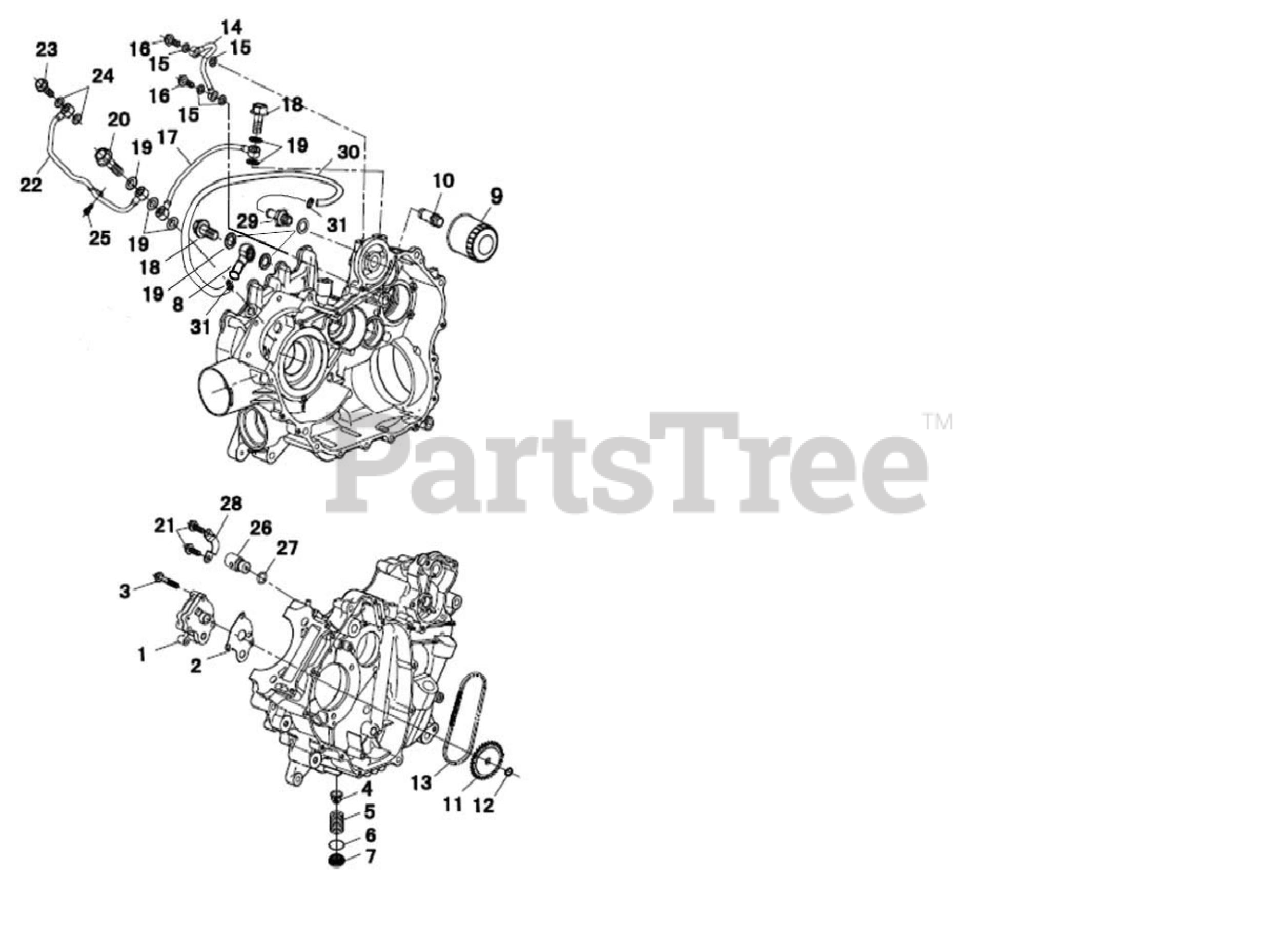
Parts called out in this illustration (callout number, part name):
1	Oil Pump Assy
2	Gasket,Oil Pump
3	Hex flange bolts M6X40
4	Oil Filter Strainer
5	Filter Spring
6	O-Ring 36X3.5
7	Blind Nut,Oil Drainage
8	BANJO BOLT
9	Oil Filter
10	Filter joint
11	Oil Pump Driven Sprocket
12	Circlip for shaft ?11
13	Chain,Oil Pump
14	Oil Tube Welding Assy A
15	Aluminum Washer 8X15X2
16	Bolts for oil tube M8X25
17	Oil Tube Welding Assy B
18	Bolts for oil tube M14X1.5X28
19	Aluminum Washer 14X20X1.5
20	Bolts for oil tube M14X1.5X50
21	Hex flange bolts M6X14
22	OIL TUBE WELDING ASSEMBLY
23	Bolts for oil tube M10X1.25X30
24	Aluminum Washer 10X16X1.2
25	Hex flange bolts M6X12
26	Pressure Regulating Valve Assy,Engine Oil
27	O-Ring 10X2.45
28	Press Plate,Pressure Regulating Valve
29	Oil Pipe Joint
30	RUBBER PIPE
31	Lock Clamp A
